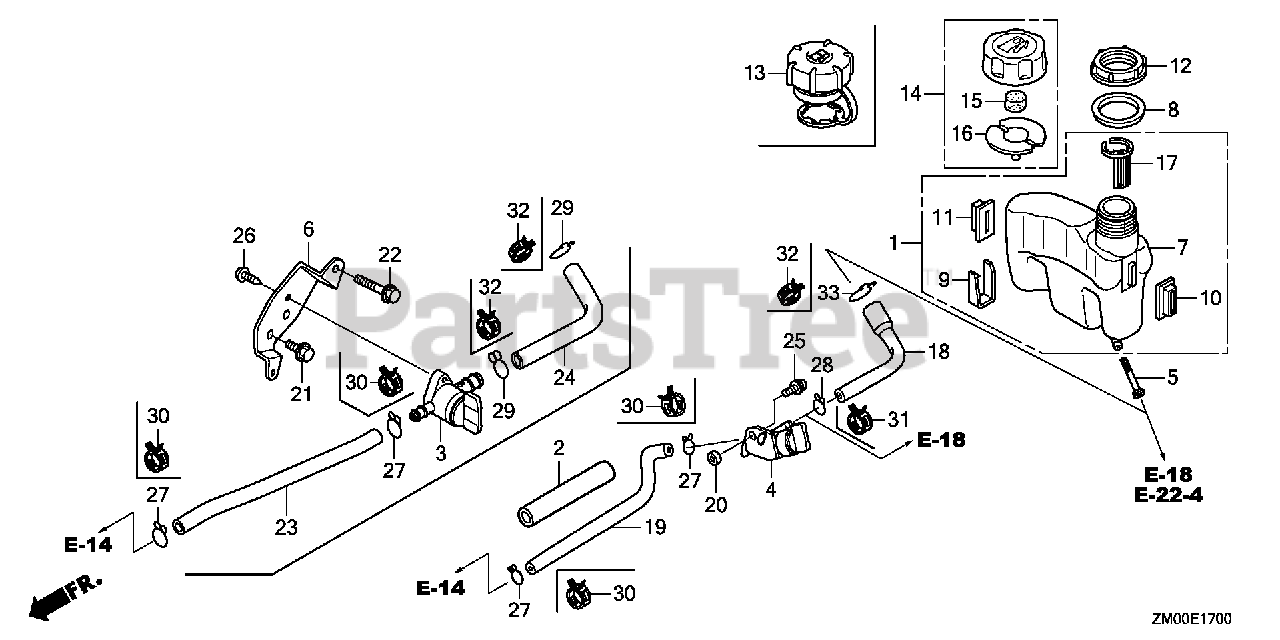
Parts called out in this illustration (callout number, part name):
2	RUBBER, SUPPORTER (107MM)
4	PETCOCK ASSY.
7	TANK, FUEL
8	SEAL, FUEL FILLER NECK
10	RUBBER A, TANK MOUNTING
11	RUBBER B, TANK MOUNTING
12	NUT, TANK MOUNTING
13	CAP ASSY., FUEL TANK
17	GAUGE, FUEL LEVEL
19	TUBE, FUEL (FKM)
20	COLLAR, FUEL PETCOCK
25	SCREW-WASHER (5X10)
30	CLIP, TUBE (D8)
